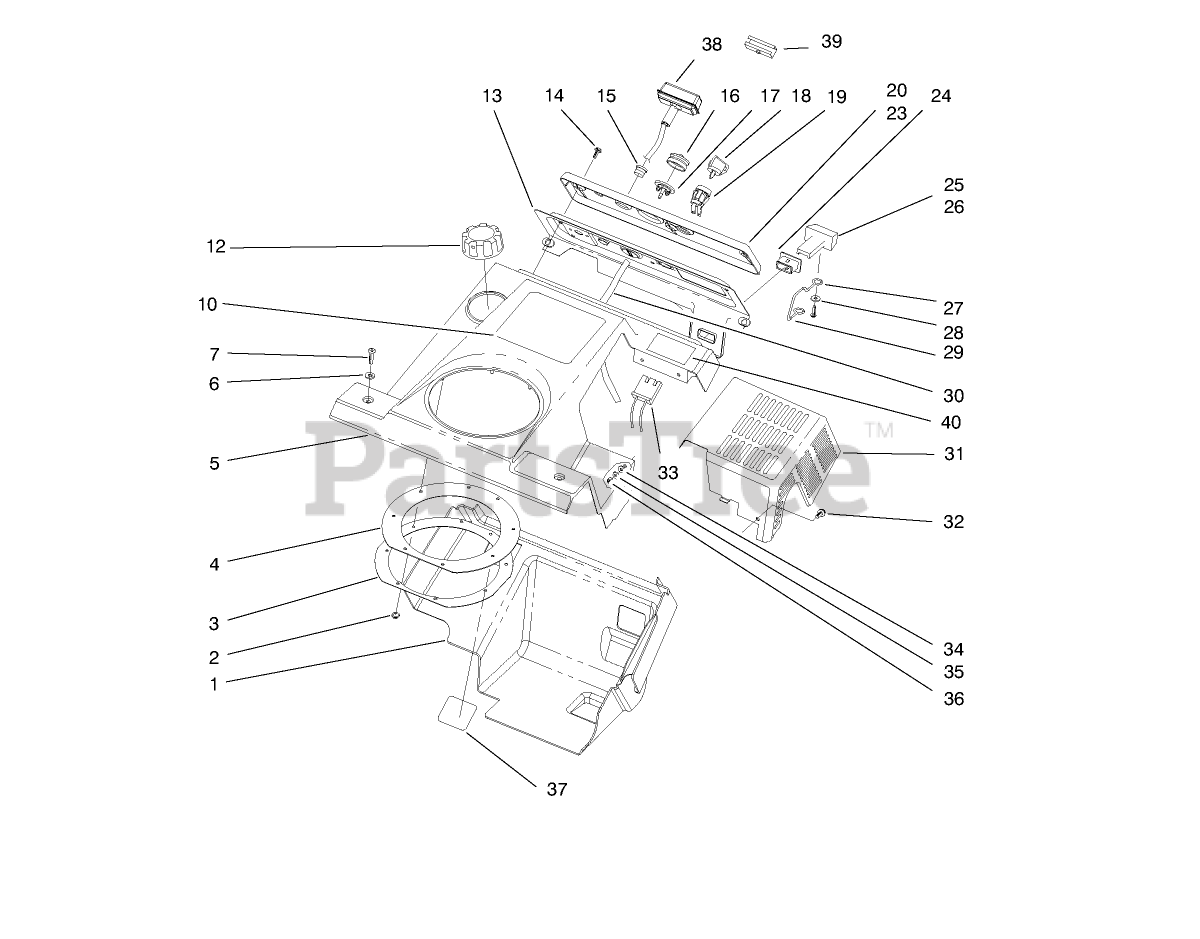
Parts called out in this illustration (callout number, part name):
2	PALNUT
6	WASHER-FLAT
7	SCREW-PPH
14	SCREW-HWH
15	GUIDE-ROPE, STARTER
16	BULB-PRIMER
17	BODY-PRIMER
18	KEY-IGNITION
19	SWITCH
20	PLATE
24	FITTING
25	CHOKE CONTROL
26	CONTROL-CHOKE
27	WASHER-PLAIN
28	SCREW-PPH
29	LINKAGE-CHOKE
30	HOSE-PRIMER
31	Shield-Heat
32	SCREW-SHH
33	CONNECTOR-BODY
34	WASHER
35	WASHER-FLAT
36	NUT-LOCK, NI
37	DECAL
39	CLIP-STARTER
